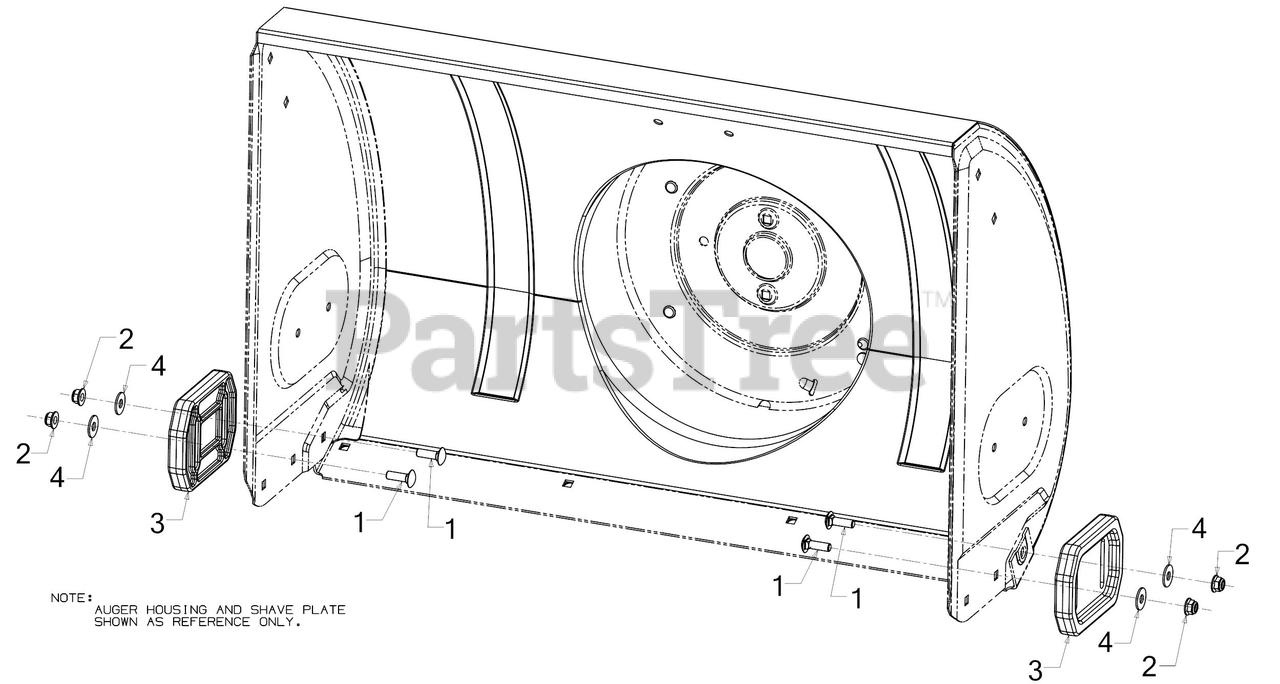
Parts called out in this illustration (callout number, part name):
1	CARRIAGE BOLT 5/16-18 x 1.00
2	FLANGE LOCK NUT 5/16-18
3	SLIDE SHOEMER
4	FLAT WASHER
